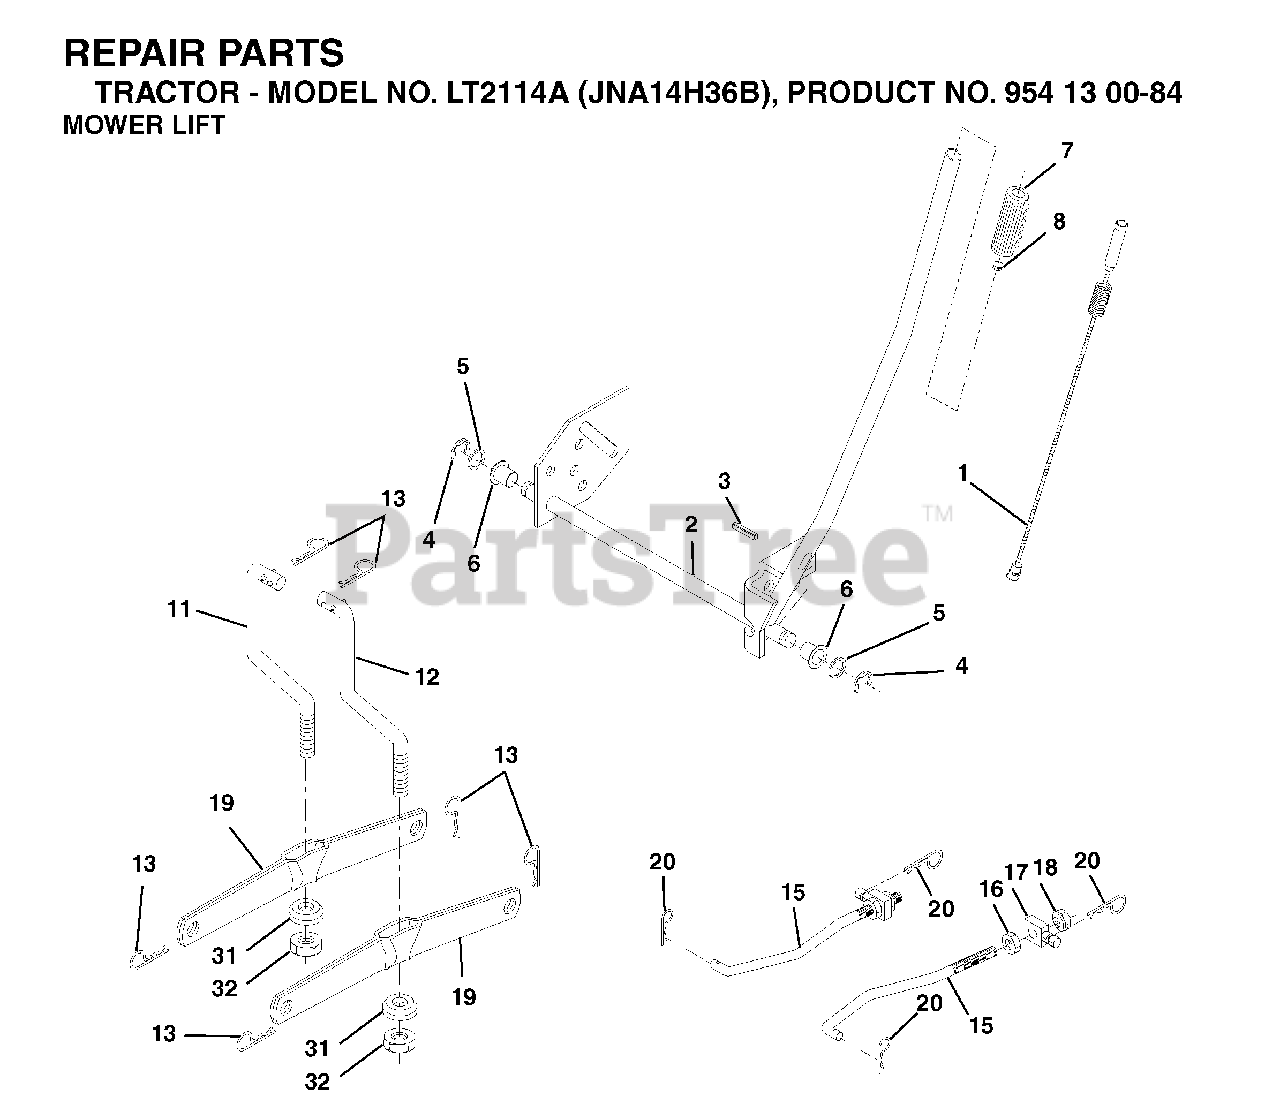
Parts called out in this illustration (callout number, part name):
1	WIRE ASM INNER W/ PLUNGER LT
2	SHAFT ASM R HANDLE
3	PIN GROOVE
4	RETAINING RING LT
6	BEARING.NYLON
7	GRIP
8	PLUNGER BUT KIT
11	LINK LIFT LH
12	LINK LIFT RH
13	RETAINER-SPRNG RB
15	LINK.SUSPENSION.FRONT
16	NUT
18	NUT
19	ARM.REAR.SUSPENSION
20	SPRING RETAINER
31	BEARING.PIVOT.LIFT
32	NUT CROWNLOCK 3/8-24
